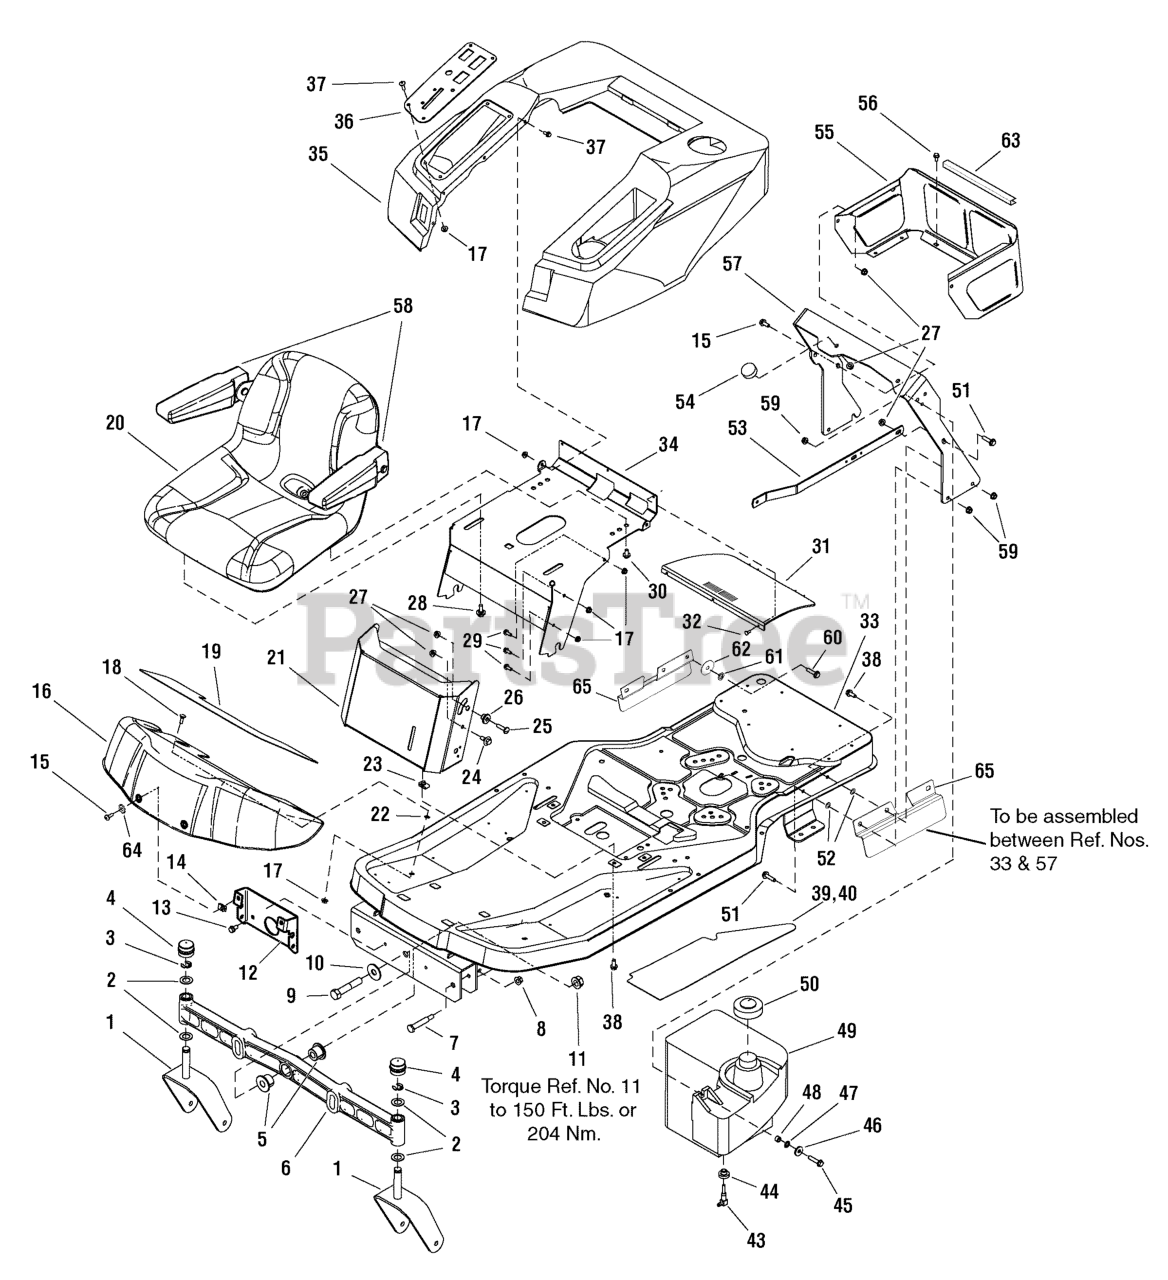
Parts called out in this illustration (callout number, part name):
1	CASTER ASSEMBLY
2	WASHER, 3/4 ID x 1.6 OD x .05 THK
3	RING, Klipring, 3/4
4	CAP, Hub
5	BUSHING, Axle Pivot
6	AXLE, Casting
7	BOLT, Shoulder, G5
8	NUT, Hex Flange, 3/8-16 ESNA
9	CAPSCREW, Hex Head, 5/8-11 x 3 1/4
10	WASHER, 5/8, .64 ID x 1-3/4 OD x .11 THK
11	NUT, Hex Flange Two-Way Lock, 5/8-11
12	BRACKET, Front Footrest Support
13	SCREW, Hex Head Taptite, 5/16-18 x 5/8
14	NUT, Speed Lug Type, 1/4-20
15	CAPSCREW, Hex Head, 5/16-18 x 1
16	FRONT FOOTREST Sears 6000 Craftsman Red
17	NUT, Hex Flange, 1/4-20 ESNA
18	CARRIAGE BOLT, 1/4-20 x 3/4, G5
19	PAD, Footrest Panel
20	SEAT ASSEMBLY, with Armrests
21	PANEL, Front - Manual Brake and Deck Lift
22	NUT, Push, 1/4
23	NUT, Speed, Lug Type, 5/16-18
24	BOLT, Shoulder
25	BOLT, Carriage, 5/16-18 x 1 1/4
26	PIVOT, Hood, Powdered Metal
27	NUT, Hex Flange Whiz Lock, 5/16-18
28	BOLT, Shoulder, G5
29	SCREW, Hex Whiz Lock Flange, 1/4-20 x 5/8
30	SCREW, Hex Flange Whiz Lock, 5/16-18 x 3/4 Dog PT
31	SCREEN, Seat Deck
32	RIVET, Pop
33	FRAME ASSEMBLY
34	SUPPORT, Seat
35	SEAT DECK, Plastic Sears Craftsman Red ZTS
36	PLATE, Control
37	SCREW, Truss Head Torx, 1/4-20 x 3/4
38	SCREW, Hex Whiz Lock Flange, 5/16-18 x 3/4
39	PAD, Footrest R.H.
40	PAD, Footrest L.H.
43	ELBOW, Gas Tank
44	BUSHING, Fuel
45	CAPSCREW, 5/16, 18 x 1-1/2
46	WASHER, 5/16, .34 ID x 1 OD x .13 THK
47	LOCKWASHER, External Tooth, 3/8
49	TANK, Fuel
50	CAP, Fuel Tank
51	CAPSCREW, Hex Head, 5/16-18 x 1 1/4
52	NUT, Push Pal, 5/16 DIA Thread, 5/8 OD
53	BRACE, Tank
54	BUMPER, Rubber
55	SHROUD, Rear
56	SCREW, Hex Washer Head Taptite, 1/4-20 x 1/2
57	SUPPORT, Seat Deck
58	ARM REST KIT, L.H. & R.H.
59	NUT, Hex Flange Nylock, 5/16-18
60	CAPSCREW, 3/8 - 16 x 1-1/4
61	NUT, Push Pal, 3/8
62	WASHER, 3/8
63	TRIM, 8"
64	WASHER, External Tooth, 1/4
65	GUARD, Debris
